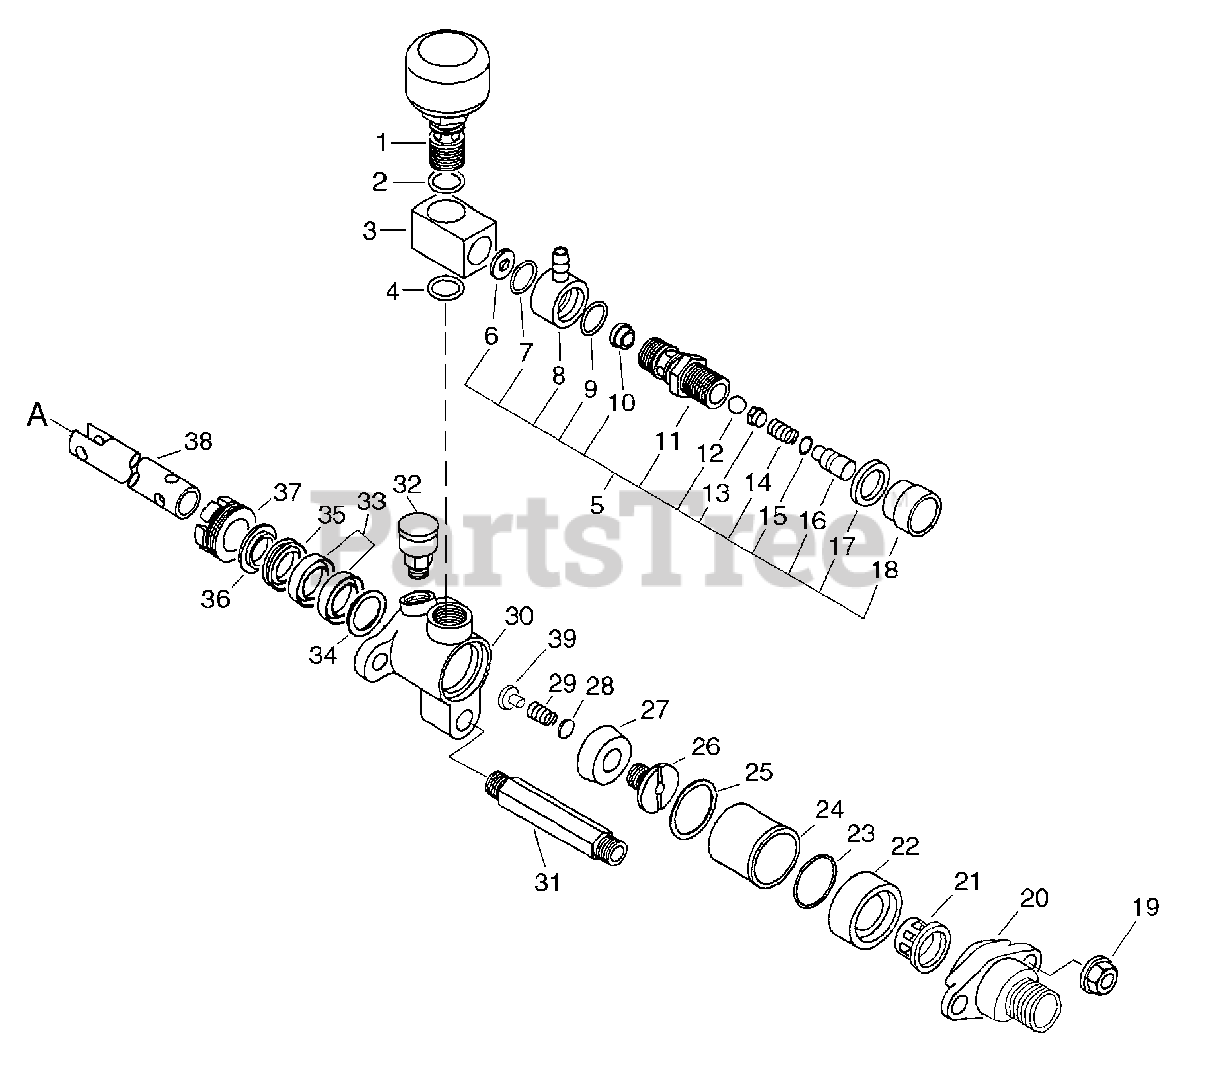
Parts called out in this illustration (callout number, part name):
1	CHAMBER, AIR
3	CONNECTOR
5	REGULATOR ASSY
8	CASING, VALVE
10	SEAT, VALVE
11	CASING, SPRING
12	HOLDER, SPRING
13	VALVE, BALL
14	SPRING, PRESSURE
16	SHAFT, REGULATOR
17	NUT, LOCK
18	CAP, REGULATOR
20	PIPE, INTAKE
21	VALVE ASSY
22	CASING, VALVE
26	SEAT, VALVE
27	PACKING, PISTON
29	SPRING, VALVE
30	CYLINDER
32	CUP ASSY, GREASE
33	PACKING SET
35	PACKING, GREASE
38	PLUNGER SET, W/SPRING HOLDER
39	HOLDER, SPRING
